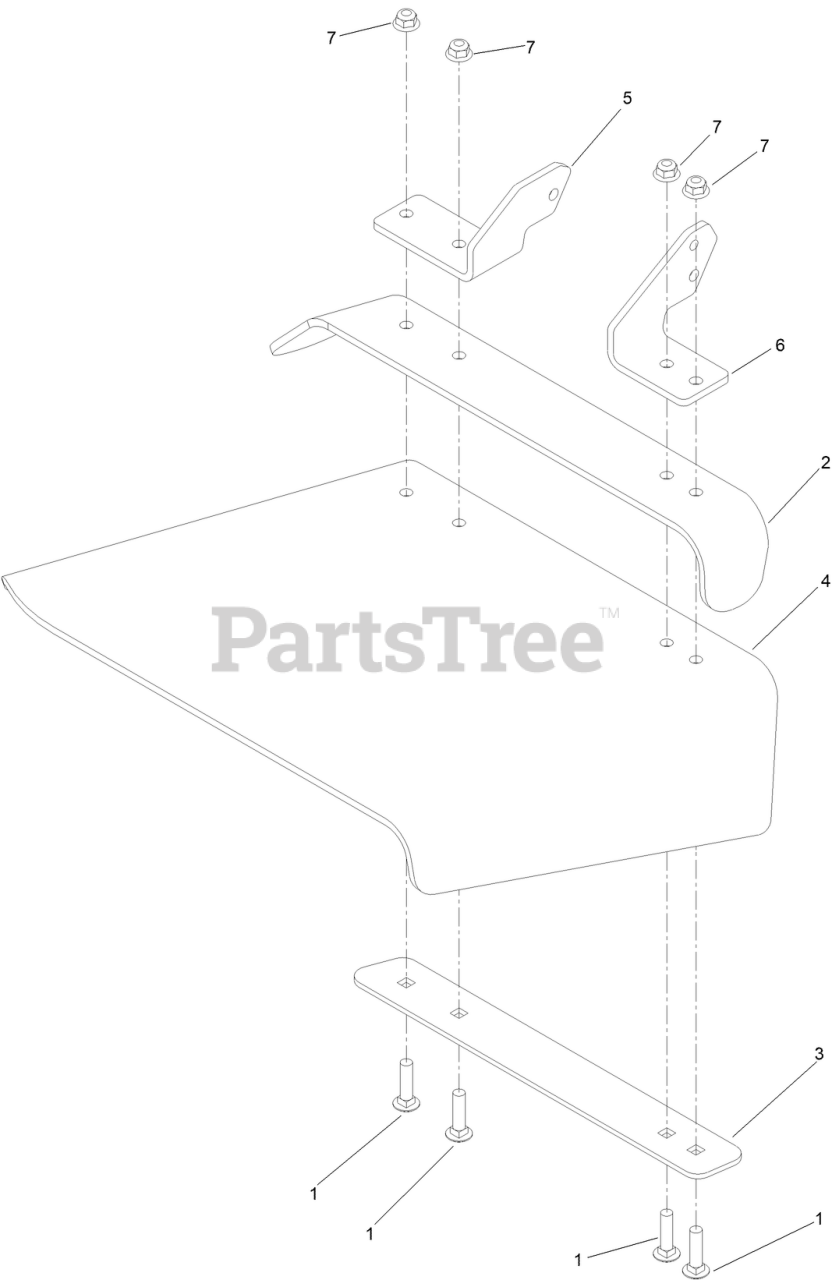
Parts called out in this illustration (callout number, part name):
1	SCREW-CARR
2	DEFLECTOR
3	STRAP-DISCHARGE
4	DEFLECTOR-DECK, RUBBER
5	PLATE-HINGE, REAR
6	PLATE-HINGE, FRONT
7	NUT-HF, NI
